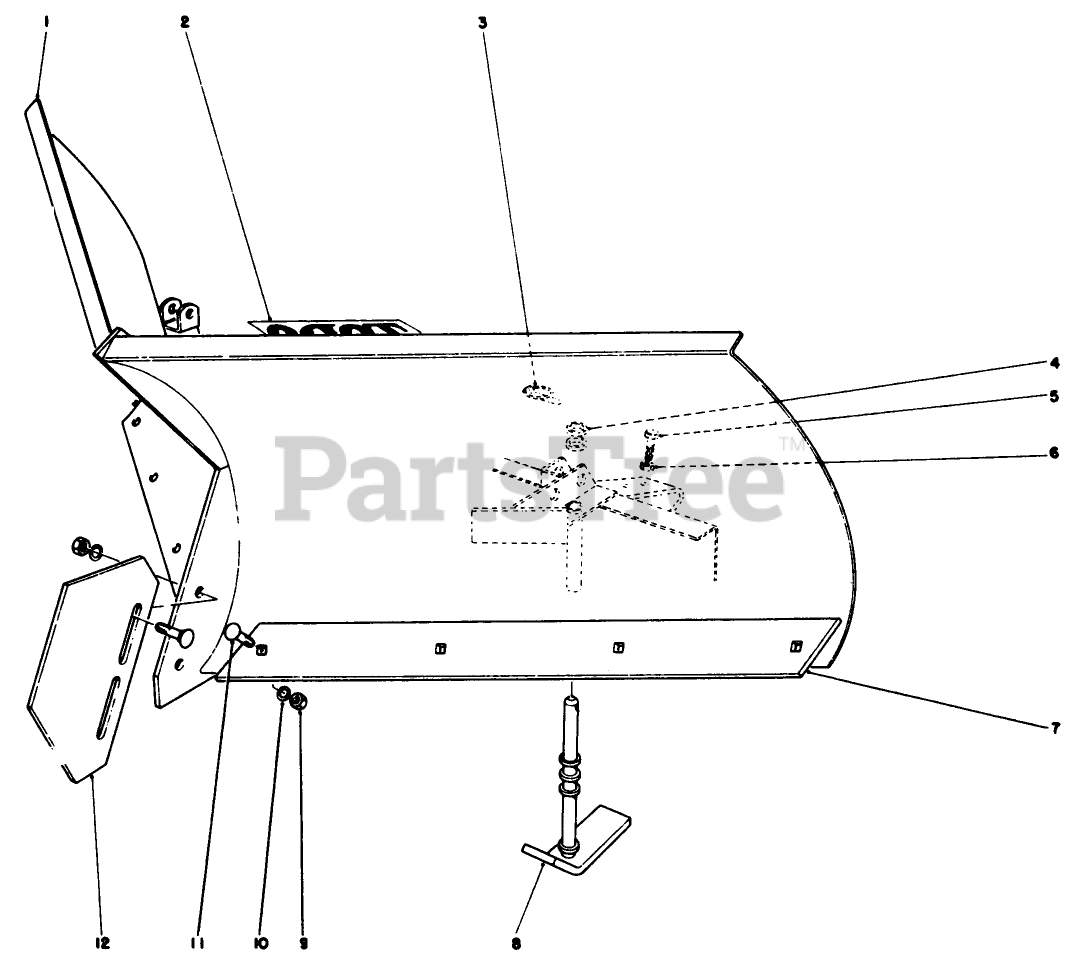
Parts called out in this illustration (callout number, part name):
3	PIN-LYNCH
4	SPACER-TUBULAR
5	SCREW-HH
6	NUT-JAM
9	NUT-HH
10	SCREW-HH
11	SCREW-HH
